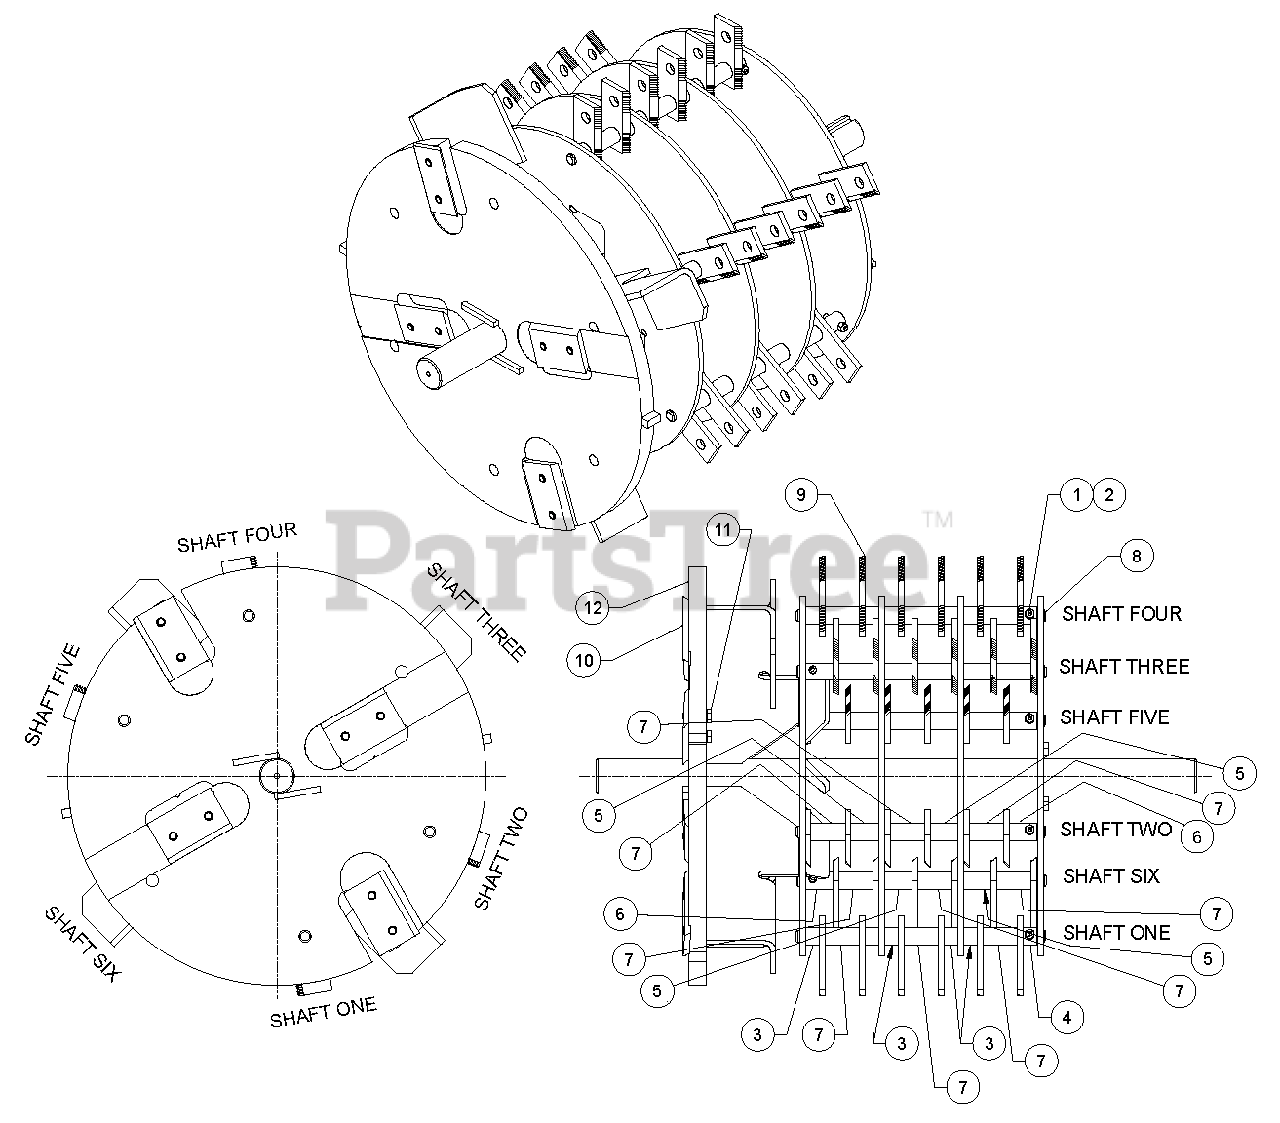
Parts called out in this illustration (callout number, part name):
1	NUT, # 10 X 24 NYLOCK
2	SCREW, 10-24 X 1-1/8"
3	SHORT SPACER .75 X .59 (LARGE C/S)
4	SHORT SPACER .75 X .59 W/HOLE (LARGE C/S)
5	SPACER, .75 X 1.18
6	MEDIUM SPACER-BORED .75 X 1.18 W/HOLE (LARGE C/S)
7	LONG SPACER .75 X 1.47 (LARGE C/S)
8	ROTOR KNIFE SHAFT (LARGE C/S)
9	SHREDDING KNIFE, RECTANGULAR (FOR SERVICE ORDER KIT #70972-00, SHREDDER KNIFE)
10	BLADE, TWO EDGE CHIPPER (FOR SERVICE ORDER KIT #72493, CHIPPER BLADE)
11	BOLT, 5/16" X 1" HEX HD.
12	5 INCH C/S ROTOR WELDMENT
